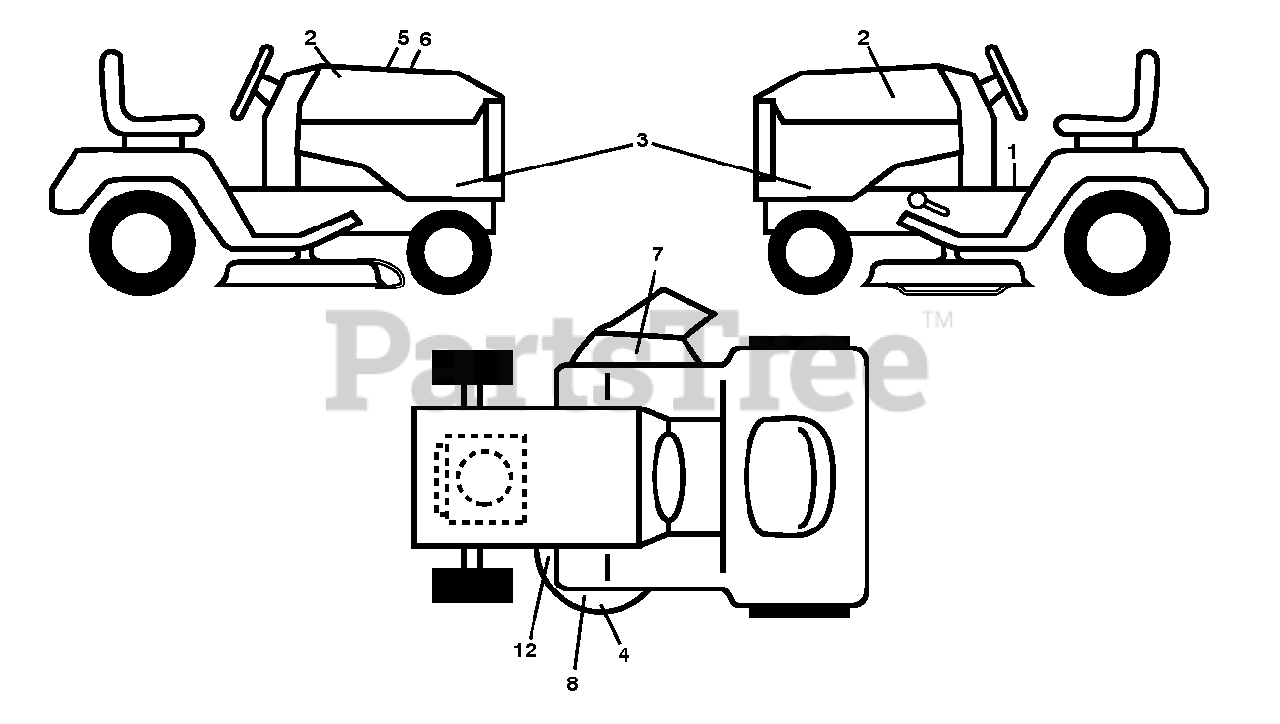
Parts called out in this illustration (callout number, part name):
1	DECAL.FENDER.WARNING.ENGLISH
2	Decal, WB 178MM 15 Husqvarna NEWBRAN
3	DECAL.SIDE.PANEL.YTH24K48
4	DECAL.MOWER.CAUTION.TENSION.AR
5	DECAL.WARNING.CUST.RESP.E85.
6	Decal, Replacement Kohler KT7 TLW 48E K46
7	DECAL, DECK DEFLECTOR, WARNING
12	DECAL.MOWER.SCH.48/54.PREM
